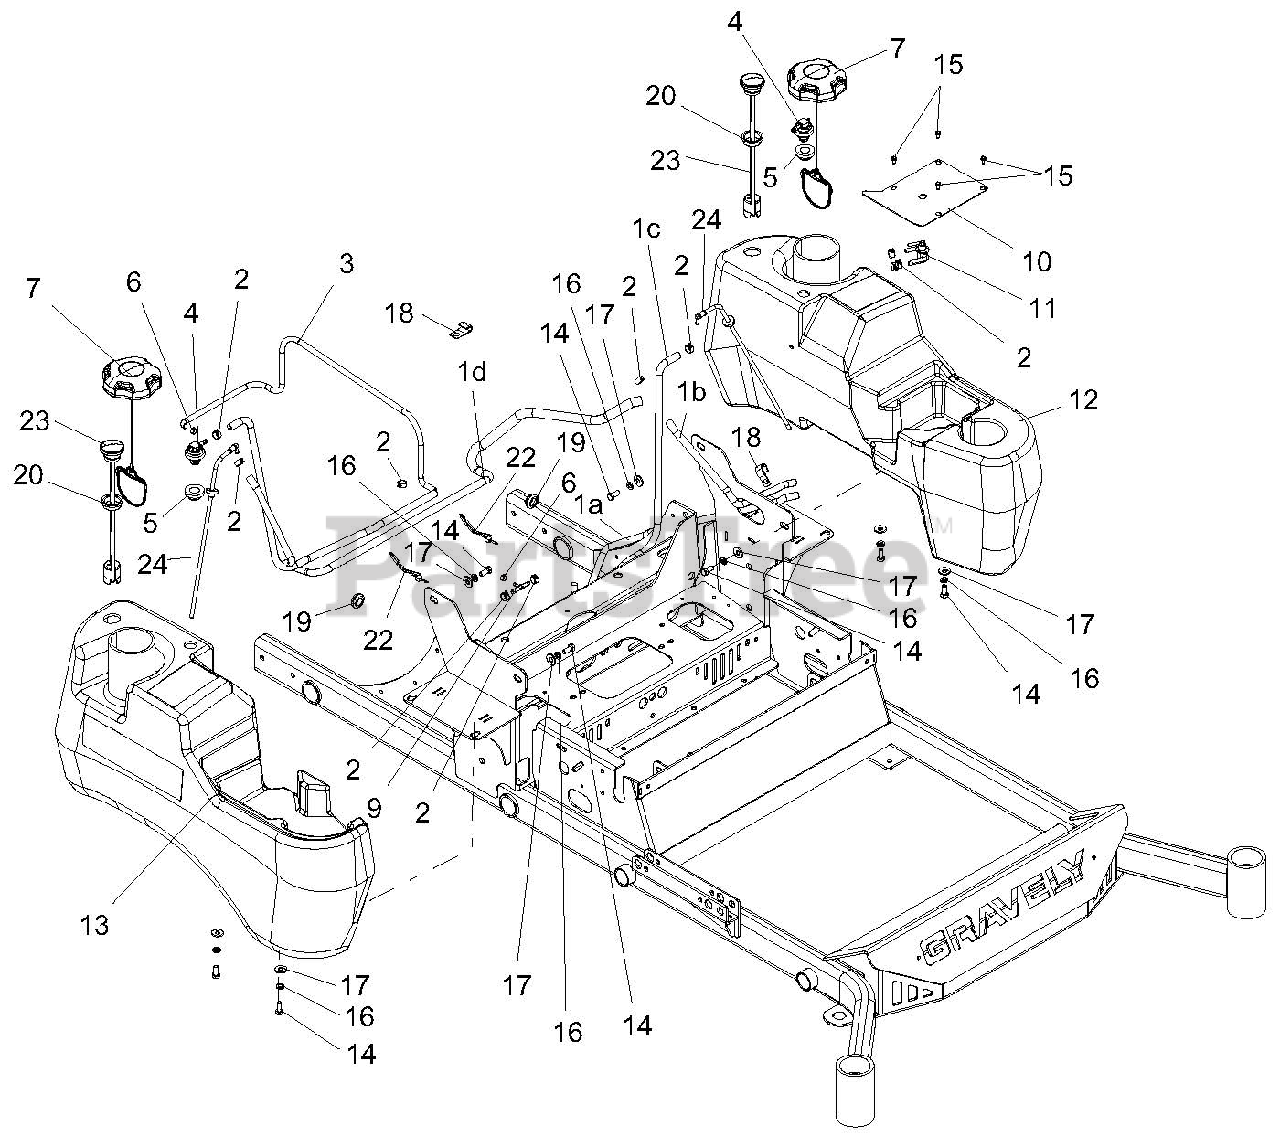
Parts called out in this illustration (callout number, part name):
2	CLAMP, FUEL LINE
3	HOSE, .188 LOW-PERM BULK GAS
4	VALVE, COMBINATION
5	GROMMET, REMOTE VENT NITRILE
6	CLAMP - HOSE, SPRING .188
7	CAP, 3.50" VENT-IN RATCHET FUEL
9	TEE, 1/4 HOSE RUN X 3/16 HOSE BRANCH
10	PLATE, FUEL VALVE MOUNTING
11	VALVE, FUEL
12	TANK, LH LARGE FUEL
13	TANK, RH LARGE FUEL
14	BLT-HEX .31-18X.75 GR5 YWZC
15	SCR, HWH 10-24x.38 STAINLESS
16	WSHR-LK .31X.078 REG YWZC
17	WSHR-FL-STL.38X.875X.083 YWZC
19	GROMMET, RUBBER
20	GROMMET, FUEL GAGE
22	CABLE TIE W/ TREE, .25 HOLE
23	GUAGE, REMOTE FUEL, 12"
24	ASSEMBLY, LARGE TANK FUEL PICKUP
